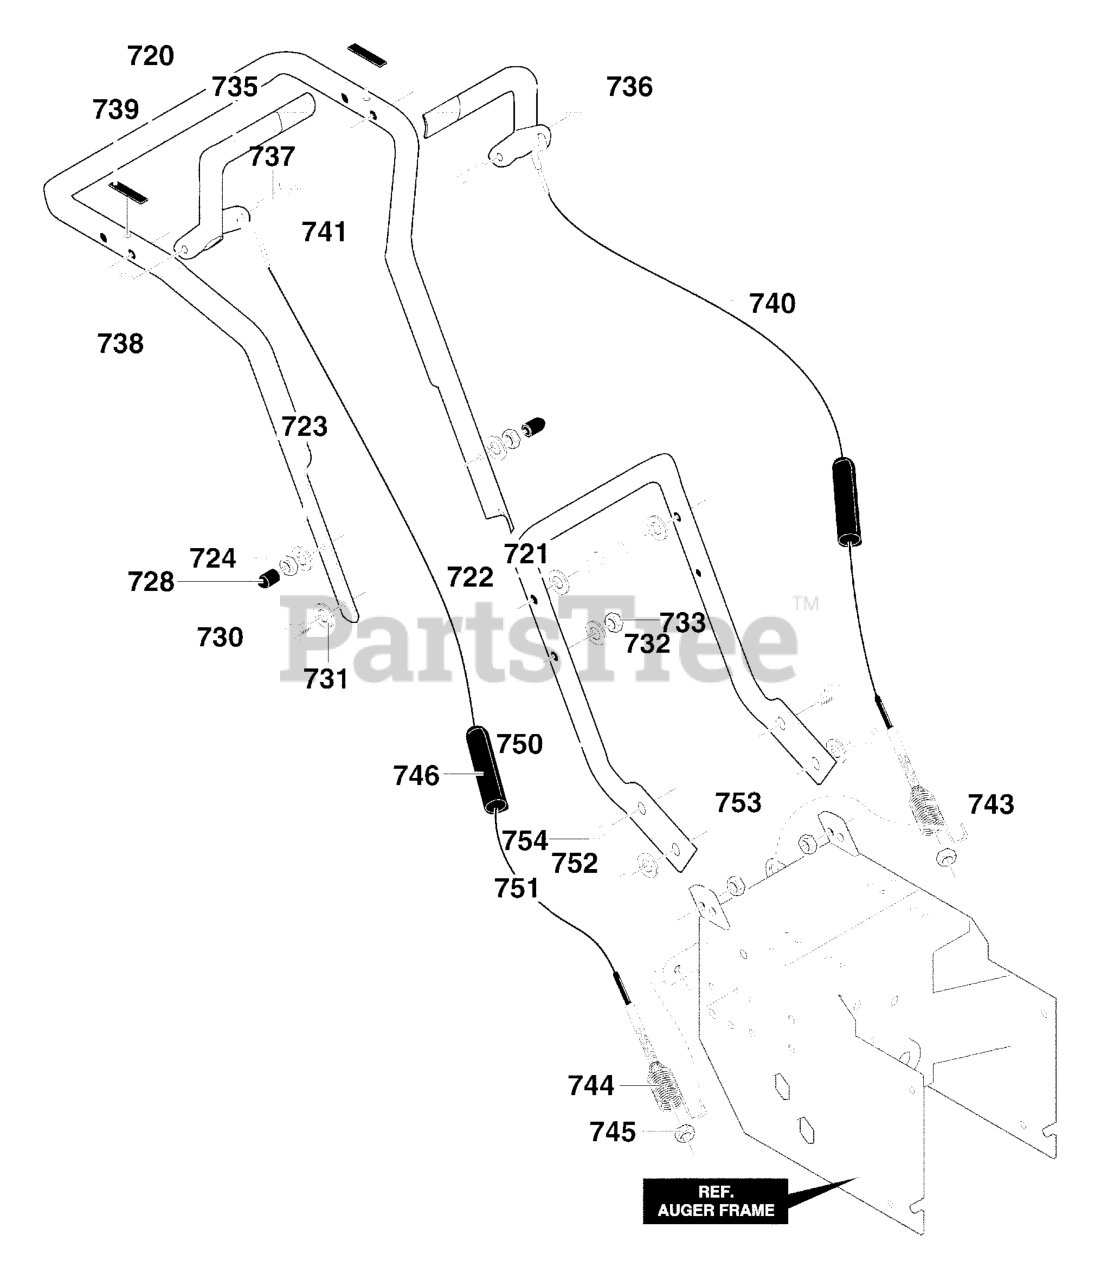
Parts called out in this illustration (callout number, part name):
720	HANDLE, UPPER LOOP
721	SCREW, 3/8-16 x 3.00
722	WASHER, FLAT
724	NUT, 3/8-16
728	STOP, PLASTIC
730	SCREW, 3/8-16 x 2.00
731	WASHER, FLAT
733	NUT, 3/8-16
735	HANDLE, RIGHT
736	HANDLE, LEFT
737	PIVOT CLUTCH PIN
738	PUSH ON CAP
739	BUMPER, RECTANGLE
740	CABLE, CLUTCH 28.44L
741	CABLE, AUGER CLUTCH
743	TENSION SPRING
744	SPRING, AUGER CLUTCH
745	NUT, 1/4-20
746	BOOT, CLUTCH SPRING
750	HANDLE, LOWER
751	SCREW, 5/16-18 x 0.75
752	WASHER
753	NUT, 5/16-18
754	SCREW, 5/16-18 x 0.75
